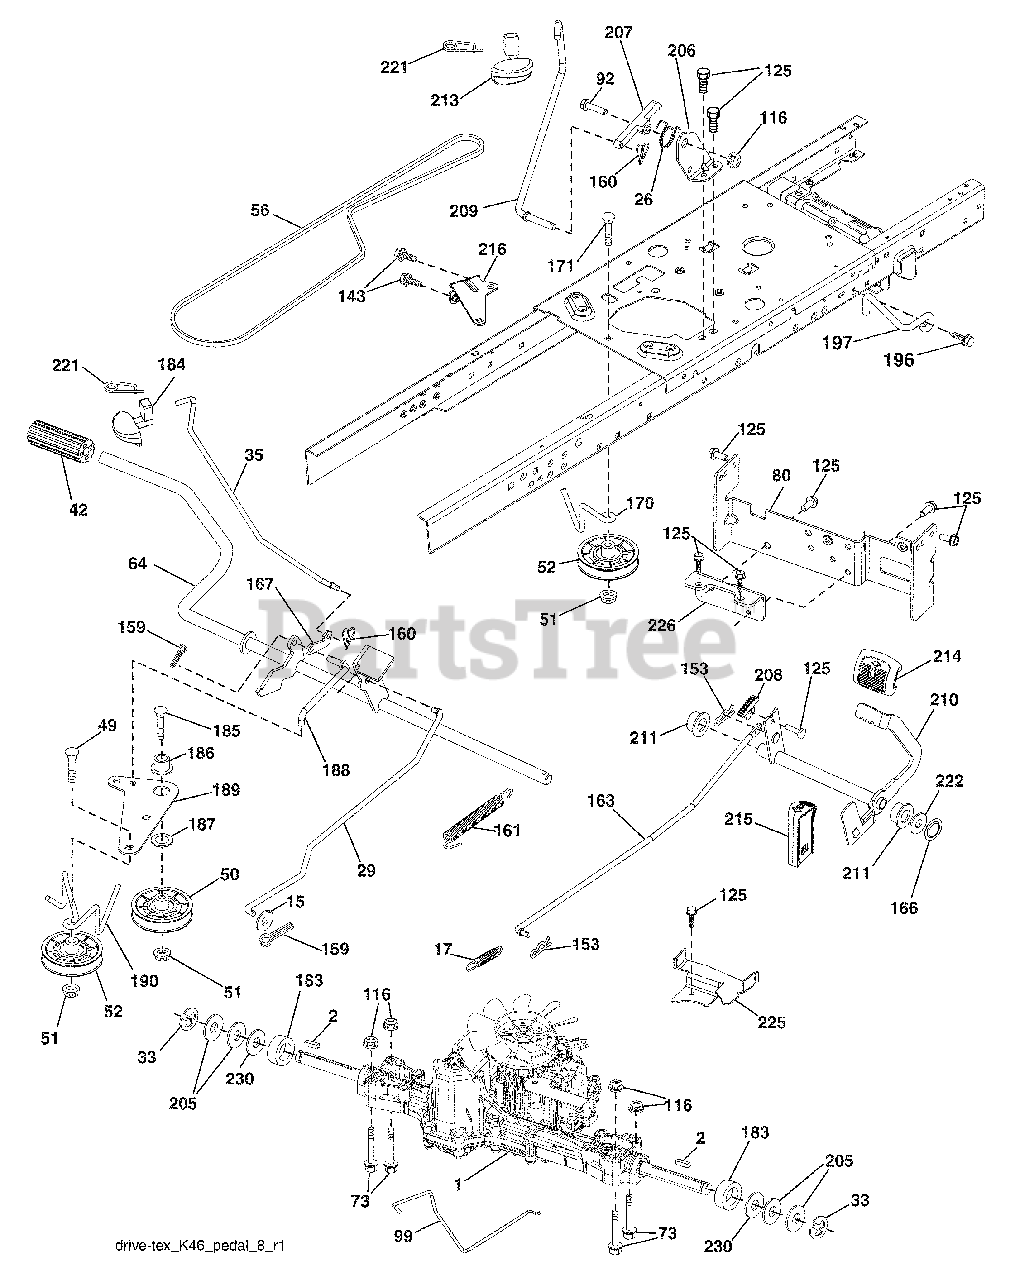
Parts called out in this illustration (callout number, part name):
1	Transaxle, TUFFTORQ K46 BT
15	Washer 13/32 x 13/16 x 16 Ga.
17	Spring, Brake
26	Spring Return Cruise
29	Rod, Brake
35	Rod, Brake, Park
42	Cover, Foot Pedal
50	Pulley Idler Flat
51	Lock Nut 3/8-16
52	Idler V-Groove 910" Offset
56	V-Belt, Drive
64	Shaft Asm. Pedal Brake Control
73	Bolt Hex Flghd 5/16-18 Gr. 5
80	Bracket Strap Torque
92	Bolt Fin Hex 5/16-18 unc x 1.25
99	Rod Spring Bypass
116	Nut Lock Hex Flange 5/16-18
125	Screw 5/16-18 x 3/4
143	Screw 5/16-18 x 1/2
153	Retainer Spring
159	Pin Cotter 1/8 x 3/4
160	Retainer Clip
161	Spring, Return, Clutch
163	Rod Pedal Control
166	Nut Push
167	Latch Brake Parking
170	Keeper Belt Centerspan
171	Bolt RDHD SQNK 3/8-16UNC x 2
183	Spacer Split
184	Handle Parking Brake
185	Bolt Rdhd Sqnk 3/8-16 x 2-1/2
186	Spacer Retainer
187	Washer
188	Link Clutch Ground Drive
189	Bellcrank Ground Drive
190	Keeper Bellcrank Ground Drive
196	Screw 3/8-16 x 1
197	Bracket Clutch Anti-Rotation
206	Bracket Mount Latch Cruise
207	Latch Control Cruise
208	Gear Sector Control Cruise
209	Rod Control Cruise
210	Rocker Asm. Pedal Control
211	Bearing Nylon
213	Knob Control Cruise
214	Pedal Forward
215	Pedal Reverse
216	Bracket Pulley Idler
221	Retainer Spring Clip Handle
222	Washer 21/32 x 1-1/4 x 10 Ga.
225	Keeper Belt Trans.
226	Bracket Mount Touque
230	Washer Hardened
